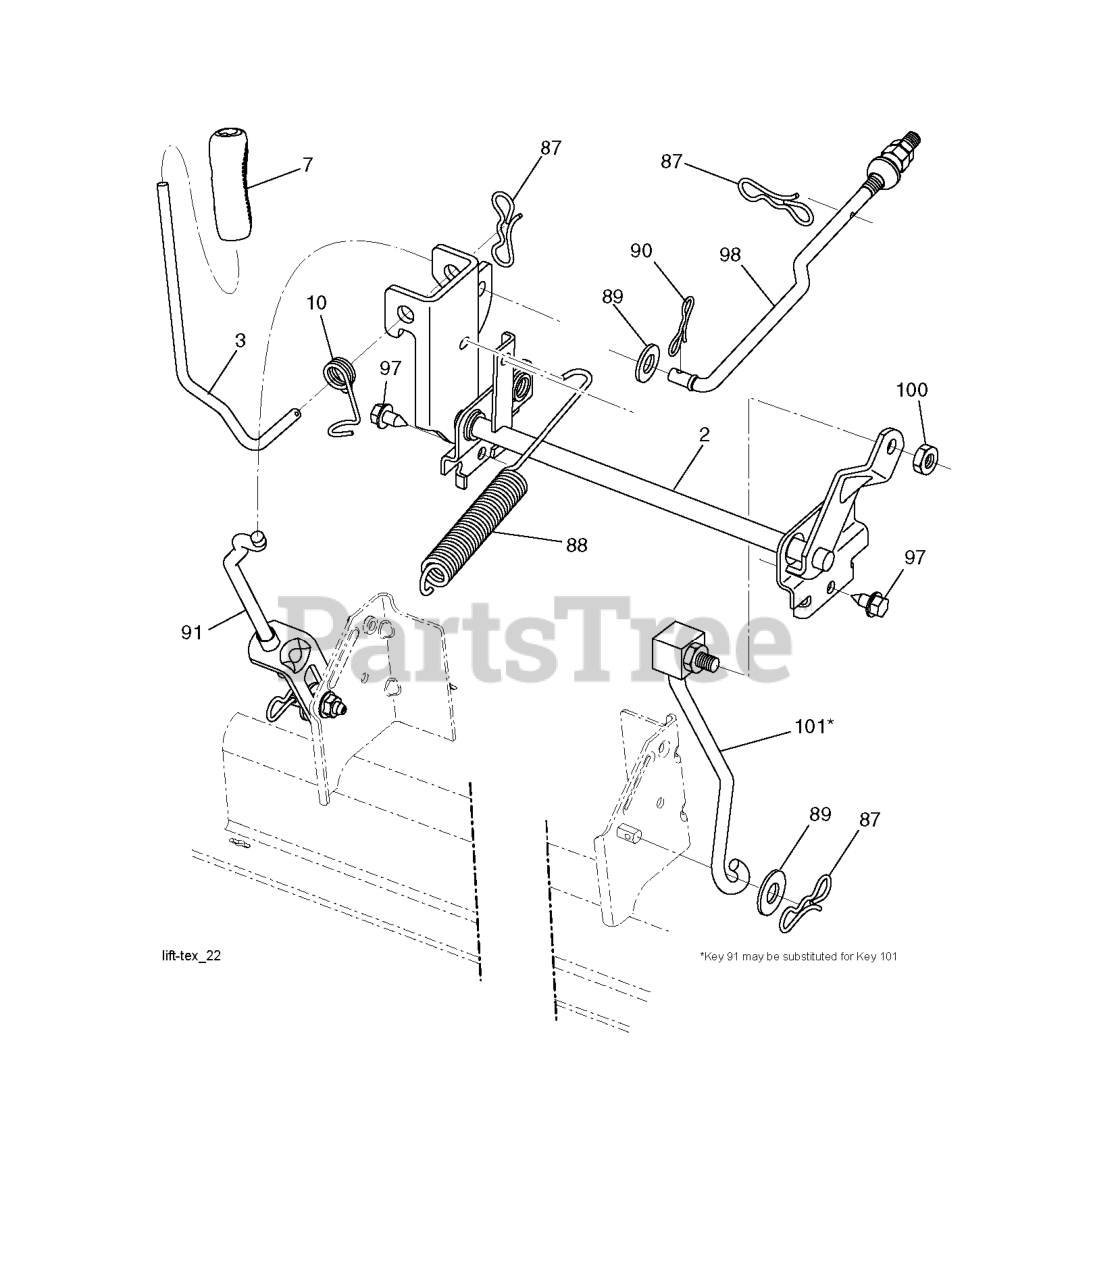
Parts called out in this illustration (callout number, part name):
2	SHAFT.ASM.CROSS.LIFT
3	LEVER.LIFT.HANDLE.LT
7	GRIP.HANDLE.LIFT.PVC.BLACK
10	SPRING.TORSION.LIFT.HANDLE
87	PIN.COTTER.7/16.BOW TI.
88	SPRING.LIFT.ASSIST
89	WASHER.CLEAR.ZINC
90	PIN.COTTER.5/16.BOW TI
91	LINK.ASM.LIFT.REAR
97	SCREW, 3/8-16X3/4
98	LINK.ASM.SUSP.FRONT.MW
100	LOCKNUT
101	LINK.ASM.LIFT.FIXE.38/42/46"
